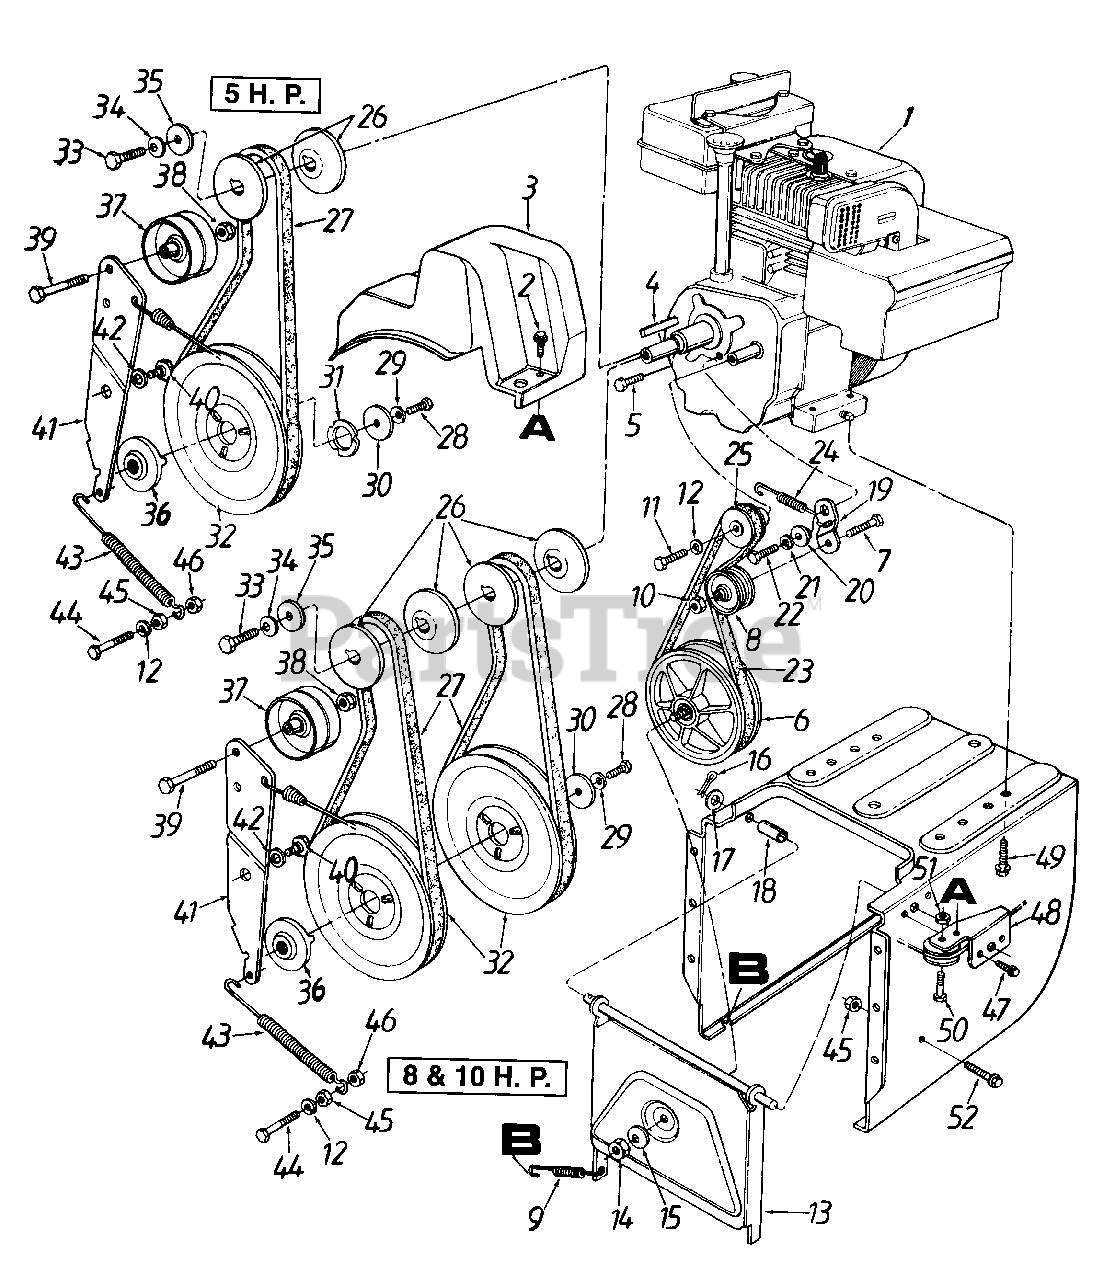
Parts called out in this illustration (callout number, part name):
1	Engine
2	Hex Wash. Hd. TT-Tap Scr. 1/4-20 x .5" Lg
3	Belt Cover
4	Sq.-Key 3/16 x 1.5" Lg.
5	Hex Patch Bolt 5/16-24 x 1" Lg. (Gr. 5)
6	Friction Wheel Disc Ass'y.
7	Hex Bolt 3/8-16 x 1.25" Lg.
8	Fl-Idler 2.12" O.D.
9	Ext. Spring 2.5" Lg.
10	Hex Top L-Nut 3/8-16 Thd.
11	Mex Bolt 1/4-28 x .5" Lg.
12	L-Wash. 1/4" I.D.
15	Bell-Wash .38" I.D. x .88" O.D.
16	Cotter Pin 1/8" x .75" Lg.
17	Fl-Wash .531" 1.D. x .93" O.D.
18	Spacer.508" I.D. x .75" O.D.
19	Drive Clutch Idler Bracket
20	Shld. Spacer .5" Dia. x .27" Lg.
22	Hex Bolt 5/16-24 x 1" Lg.
23	"V"-Belt
24	Extension Spring
25	2" Dia. Pulley
26	3/8 "V"-Pulley Half
27	"V"-Belt
28	Hex Cap L-Bolt 5/16-24 x .75" Lg.
29	Bell-Wash .345" I.D. x .88" O.D.
30	Fl-Wash .34" I D x 1.5" O.D.
31	Brg. Retaining Washer
32	Auger Pulley
33	Hex Bolt 3/8-24 x .88" Lg.
34	Bell-Wash .39" I.D. x 1.13" O.D.
35	Fl-Wash .406" I.D. x 1.25" 0 D.
36	Adapter Pulley
37	Fl-Idler 2.75" 0 D
38	Hex Ins. L-Nut 3/8-24 Thd.
39	Hex Bolt 3/8-24 x 1.5" Lg. (Gr. 5)
42	Wave Wash .66" I.D. x .88"
43	Ext. Spring 3.6" Lg
44	Hex Bolt 1/4-20 x 75" Lg. (Gr. 5)
45	Hex Nut 1/4-20 Thd.
46	Hex L-Nut 1/4-20 Thd.
47	Torx Mach. AB-Tap Scr 1/4 x .62" Lg.
50	Shld. Bolt 5/16" Dia. x .35" Lg.
51	Hex Jam Nut 1/4-20 Thd.
52	Hex Wash Hd. TT-Tap Scr. 1/4-20 x 1" Lg.
